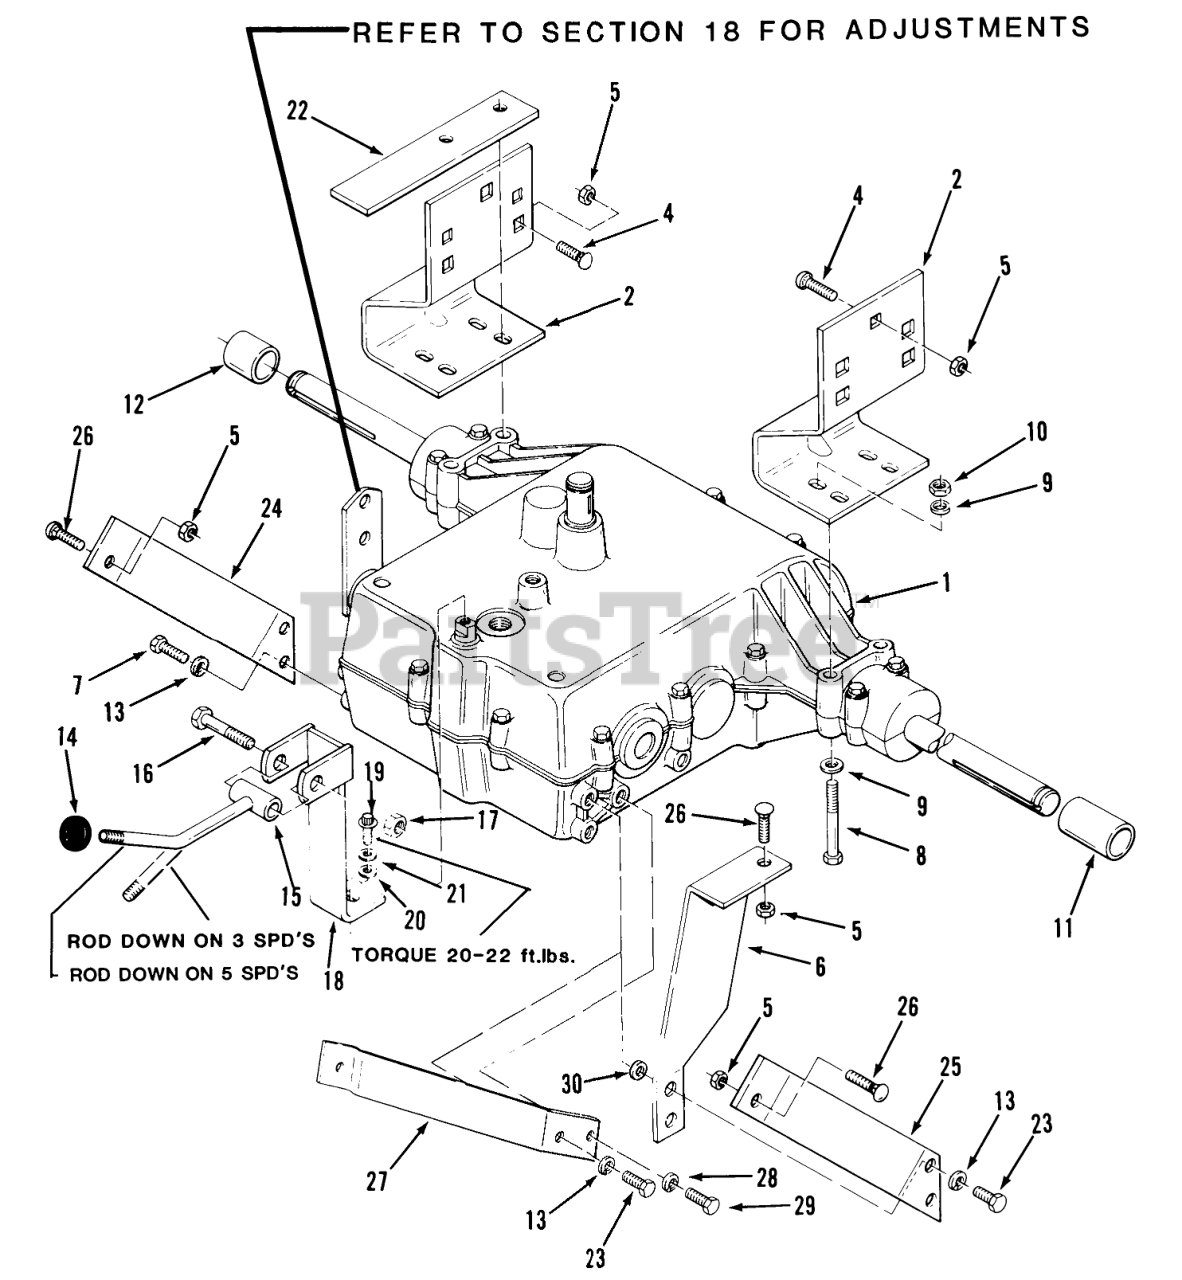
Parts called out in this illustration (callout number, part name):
1	Trans.-3-Spd.(Peerless Model 900-013)
2	Bracket-Rear Axle RH
4	Bolt
5	Nut
6	Torque Strap 3-Speed Only
7	Screw
8	HHCS
9	WASHER 5/16 SAE
10	Nut
11	SPACER
12	SPACER-AXLE RH
13	Lockwasher
15	ASSY UPPER SHIFT ROD
16	Bolt
17	Nut
18	Shift Lever-Lower 3-Speed Only
19	Bolt-12 Point-5-Speed
20	WASHER
21	WASHER SPECIAL
22	Brake Stop Bar 3-Speed Only
23	Bolt
24	TORQUE STRAP RH R
25	Torque Strap LH 211-5 Only
26	Bolt
27	TORQUE STRAP LH R
28	Washer
29	Bolt, 1/4-20 x 3/4 Swage Form
